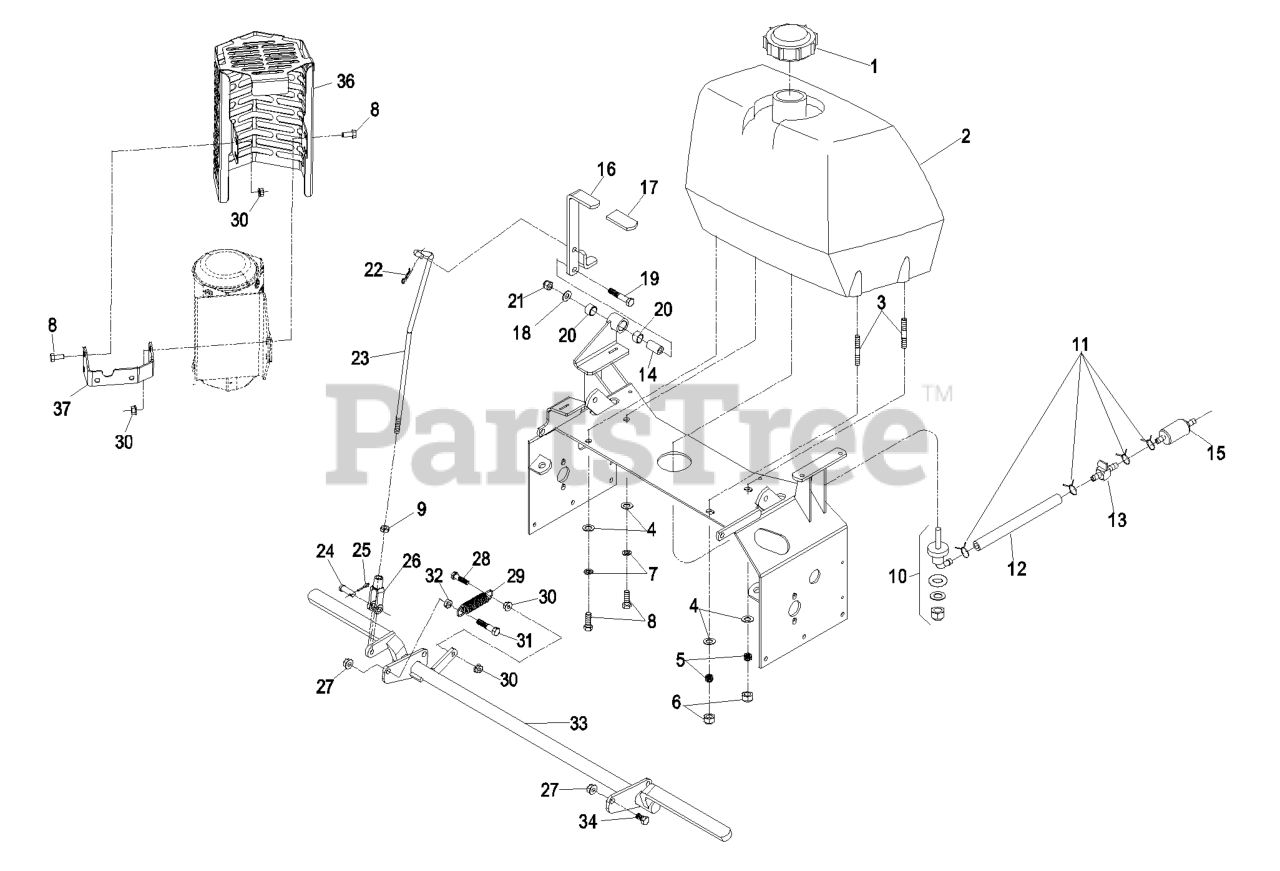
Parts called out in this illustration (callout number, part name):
1	CAP-FUEL, GAS
2	ASM,FUEL TANK W/B
3	STUD
4	WASHER-PLAIN
5	SPRING-TANK, FUEL
6	NUT-LOCK, NI
7	WASHER-LOCK
8	SCREW-HH
9	NUT-HJ
10	FITTING-FUEL, BULKHEAD
12	HOSE-FUEL
13	VALVE-FUEL
14	HOSE-FUEL
15	Kawasaki Part No. 49019-7001 Fuel Filter
16	LEVER,PRK BRK W/DECALS
17	GRIP-LEVER
18	WASHER-FLAT
19	SCREW-HH
20	SLEEVE-BUSHING
21	NUT-LOCK, NI
22	PIN-COTTER
23	LINKAGE, PARK BRAKE
24	PIN-CLEVIS
25	PIN-COTTER
26	YOKE-LINKAGE, BRAKE
27	NUT-HHF, WHIZ
28	SCREW-HH
29	SPRING-IDLER
31	SCREW-HH
32	NUT-JAM
34	SCREW-HH
35	BUSHING-PIVOT
36	MUFFLER SHIELD ASM
37	BRACKET-MUFFLER
